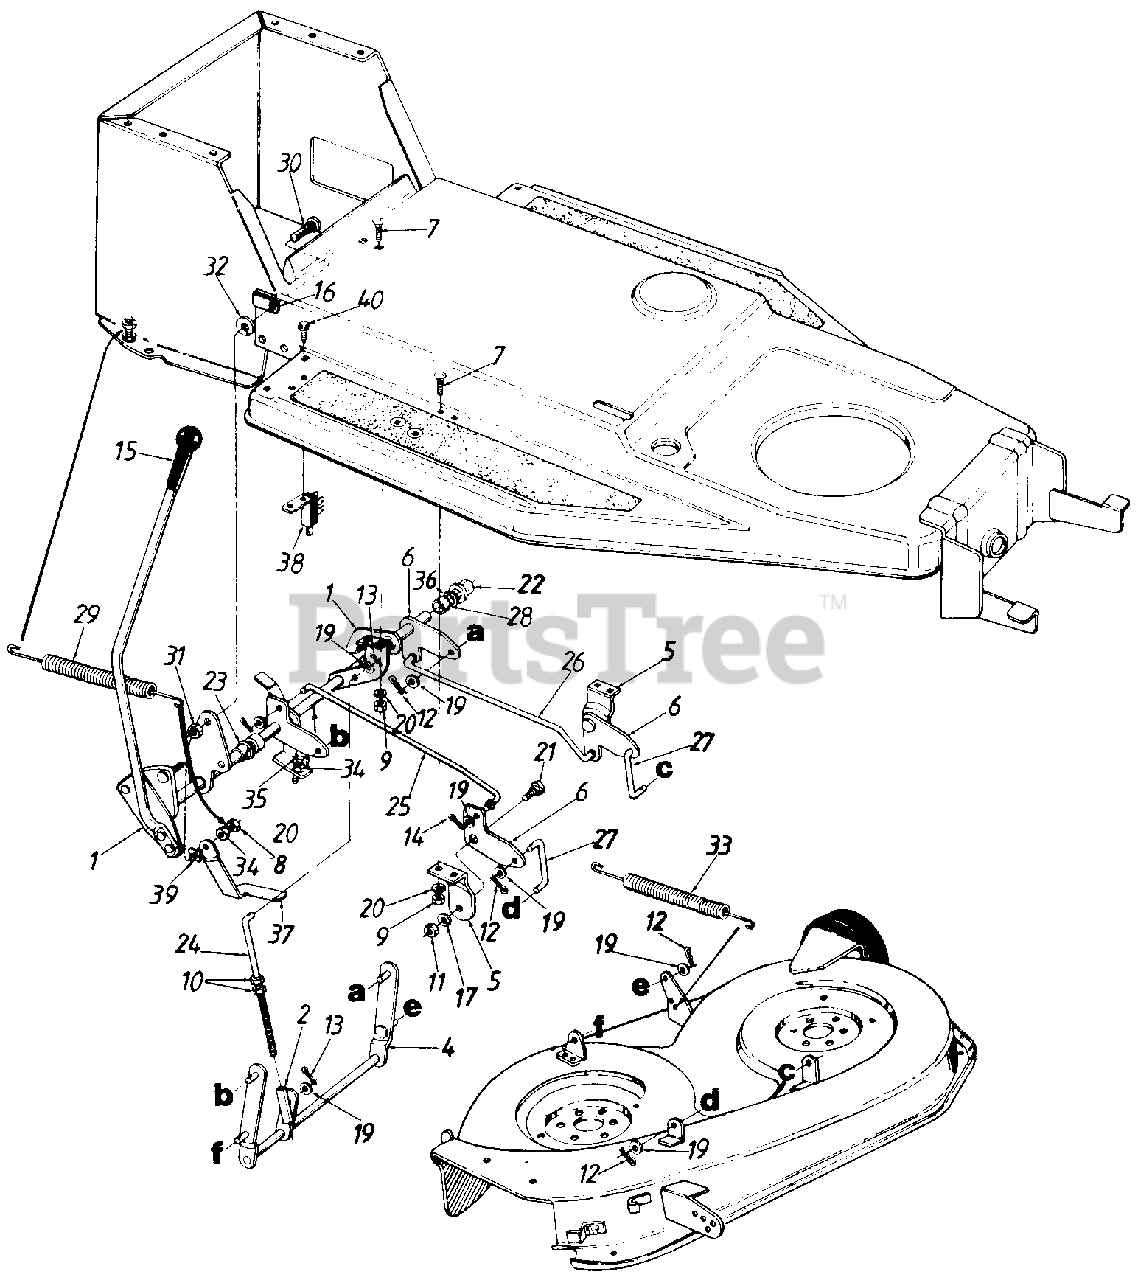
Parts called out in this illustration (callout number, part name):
1	Lift Shaft Ass'y.
2	Pivot Sleeve Ass'y.
6	Deck Lift Float Brkt.
7	Carr. Bolt 1/4-20 x .62" Lg.
8	Hex L-Nut 5/16-18 Thd.
9	Hex Nut 1/4-20 Thd.*
10	Hex L-Nut 3/8-24 Thd.
11	Hex Nut 3/8-16 Thd.*
12	Intern. Cot-Pin 5/16" Dia.
13	Cot-Pin 1/8" Dia.
14	Cot-Pin 3/32" Dia.
16	Clamp
17	L-Wash. 3/8" I.D.*
19	Fl-Wash. .406" I.D. x .75" O.D.
20	L-Wash. 1/4" I.D.*
21	Shld. Bolt .625 Dia. x .170" Lg.
22	Hex Flange Brg.
23	Nyliner Flanged Brg.
24	J-Bolt 3/8-16 x 5.25" Lg.
25	Connecting Rod-R.H.
26	Connecting Rod-L.H.
29	Spring 8.65" Lg.
30	Ribbed Neck Bolt 3/8-24 x .80" Lg.
31	Hex Nut 3/8-24 Thd.*
32	L-Wash. 3/8" I.D. H.D.
33	Deck Spring 10.33" Lg.
34	Hex Nut 5/16-18 Thd.*
35	Hex Wash. Hd. Tap Scr. 5/16-18 x 1.0" Lg.
36	Spr. Wash. .625" I.D.
39	L-Wash. 5/16" I.D.
40	Truss Mach. B-Tap Scr. #10 x .5" Lg.
